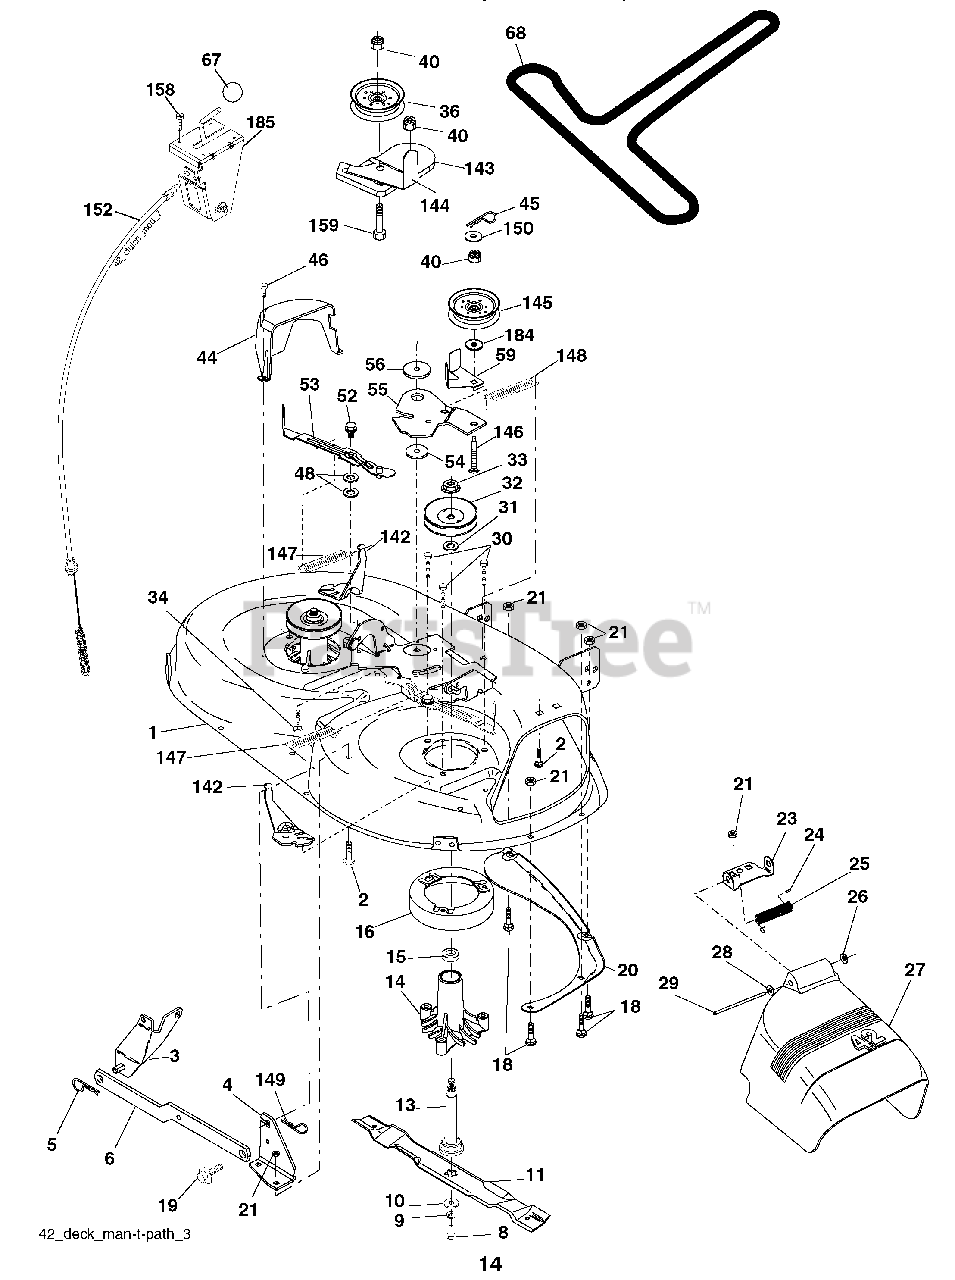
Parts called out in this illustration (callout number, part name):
1	Mower Deck Assembly, 42"
2	Bolt
3	Bracket Asm Fr. Sway Bar 3/42
4	Bracket Asm Deck 42" Sway Bar
5	Retainer Spring
6	Bar Sway Deck
8	Bolt 3/8-24 x 1.25 Gr. 8 patched
9	Washer, Lock
10	Washer, Hardened (The following Blades are available)
11	Blade Mower 42” Hi-Lift (for bagging and discharging)
11	Blade, Mulching 42” Std (for mulching mowers only)
11	Blade Mulching 42” Premium (For better wear when mulching)
13	Shaft Assembly, Mandrel, Vented
14	Housing, Mandrel, Vented
15	Bearing, Ball, Mandrel
16	Stripper, Mandrel Deck
18	Bolt, Carriage 5/16-18 x 5/8
19	Bolt, Shoulder
20	Baffle, Vortex
21	Nut
23	Bracket, Deflector Mower 42"
24	Cap, Sleeve 80 x 112 Blk Mower
25	Spring, Torsion, Deflector 2 52
26	Nut, Push Phos & Oil
27	Shield, Deflector 42" Blk
28	Washer 11/32 x 5/8 x 16 Ga.
29	Rod, Hinge 42" 6 75 W/G
30	Screw Thdrol
31	Washer, Spacer Mower Vented
32	Pulley, Mandrel
33	Nut, Toplock
34	Bolt Carr SH 3/8-16 x 1-1/2 Gr.5
36	Pulley, Idler, Flat
40	Nut Lock 3/8-16
44	Guard, Mandrel, LH
45	Retainer
46	Screw, Thdrol 1/4-20 x 5/8 T
48	Washer, Hardened
52	Bolt, Shoulder 5/16-18 unc
53	Arm Assembly, Pad, Brake
54	Washer, Hardened
55	Arm, Idler
56	Spacer, Retainer
59	Guard TUV Idler
67	Knob Round
68	V-Belt, 42" Mower
142	Arm Spring Brake Mower
143	Bracket Arm Idler 42"
144	Keeper Belt 42" Clutch Cable
145	Pulley Idler Flat
146	Bolt Carriage Idler
147	Spring Extension
148	Spring Return Idler
149	Retainer Spring Yellow
150	Washer 9/32 x 3/4 x 10 Ga.
152	Clutch Cable 42"
158	Screw Hex Thd Cut 1/4-20 x 1/2
159	Bolt Rdhd Sqn 3/8-16 unc x 1-3/4
184	Washer 13/32 x 7/8 x 10 Ga.
185	Head Asm Cable Clutch
185	Mandrel Assembly
185	Replacement Mower, Complete
